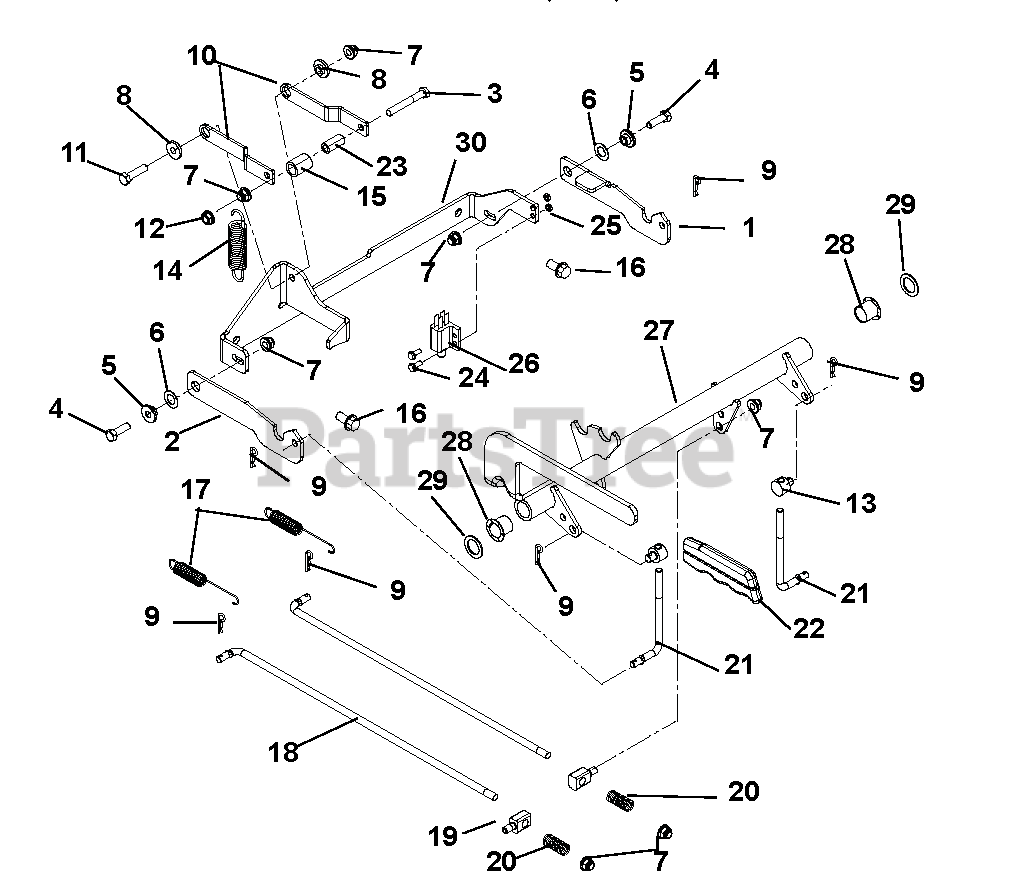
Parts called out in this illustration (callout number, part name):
1	LINK, BRAKE INTERLOCK
2	INTERLOCK, BRAKE
3	@BLT-HEX .31-18X2.25 GR5 YWZC
4	@BLT-HEX .31-18X1.00 GR5 YWZC
5	BSHG-FLG .32X.500X.344X.880
6	WSHR-FL-STL .505X.875X.024 YWZ
7	@NUT-LK-NYL-FLG .31-18 YWZC
8	BSHG, FLG .325X.499X.26X.88
9	PIN-HAIR INT .08X.18X1.18 YWZC
10	ARM, BRAKE CAM
11	@BLT-HEX .31-18X1.25 GR5 YWZC
12	@NUT-LK-TOP-FLG .31-18 YWZC
13	TRUNNION, BRAKE .31-18 UNC
14	SG-TENS .105X.812X3.88 WLD 15
15	ROLLER, CAM LOCK
16	@SCR-TAP .38-16X.75 HWH TR YWZ
17	SG-TENS .056X.60X4.40
18	ROD, PARK BRAKE
19	PIN, PIVOT/TRUNNION
20	SPRING, COMPRESSION
21	LINK, INTERLOCK BRAKE
22	GRIP, PARKING BRAKE (YELLOW)
23	BSHG, SPCR .330X.500X1.01 PM
24	SCR-MCH.25-20X.50 FLTCNTRSK SS
25	@NUT-LK-NYL 10-24 W/INSRT YWZC
26	SWITCH- DOUBLE POLE N.O./N.O.
27	SHAFT, BRAKE
28	BUSHING, IGLIDE CLIP
29	WSHR-FL-STL.754X1.125X.062YWZC
30	BRKT, BRAKE MTG
